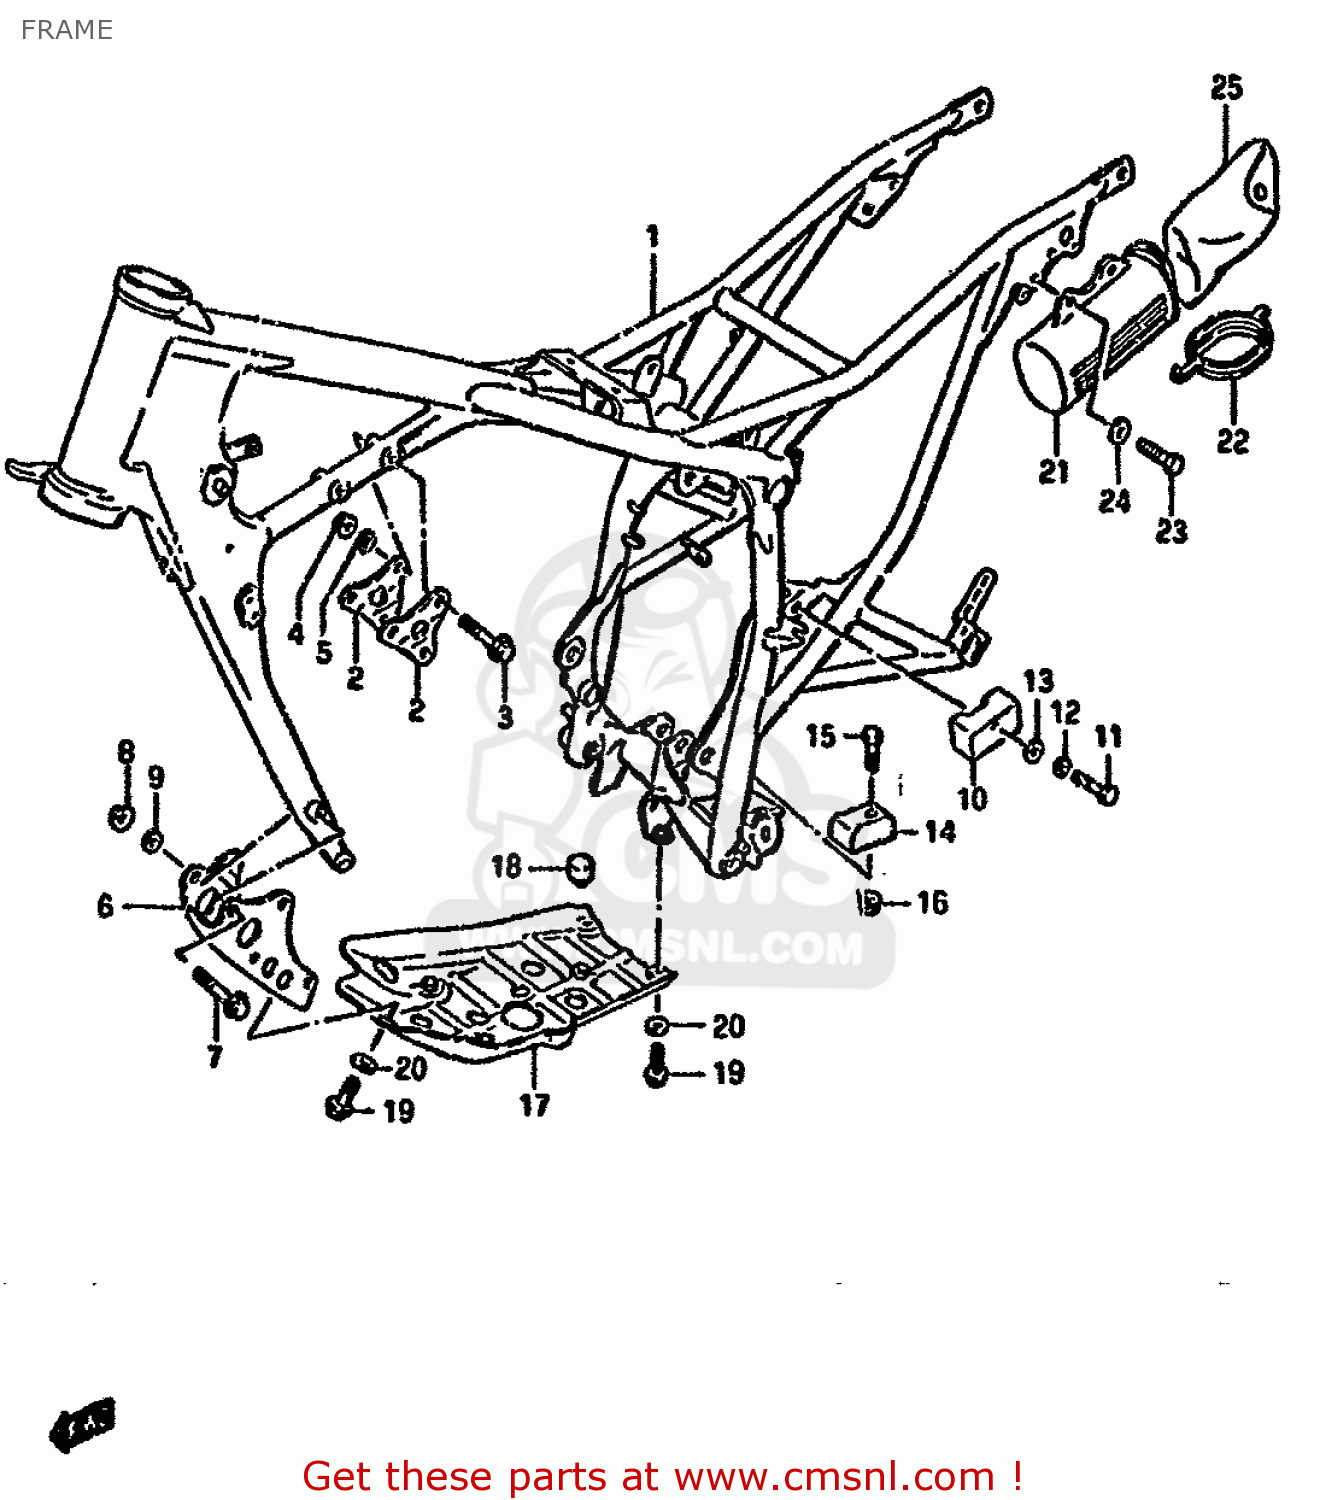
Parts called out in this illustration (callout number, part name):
1	FRAME (BLUE)
2	PLATE,ENGINE MOUNT UPR
3	BOLT
4	NUT
5	LOCK WASHER
6	PLATE,ENGINE MOUNTING
7	BOLT
8	NUT
9	LOCK WASHER
10	GUIDE,CH CONTROL UPR
11	BOLT 6X35
12	WASHER,LOCK
13	WASHER
14	GUIDE,CH LENGTH CONTROL LWR
15	BOLT
16	NUT 6MM
17	PROTECTOR,ENGINE
18	CUSHION
19	BOLT
20	WASHER
21	HOLDER,TOOL
22	CAP,HOLDER
23	BOLT 6X16
24	WASHER (6.5X18X1.6)
25	TOOL SET
